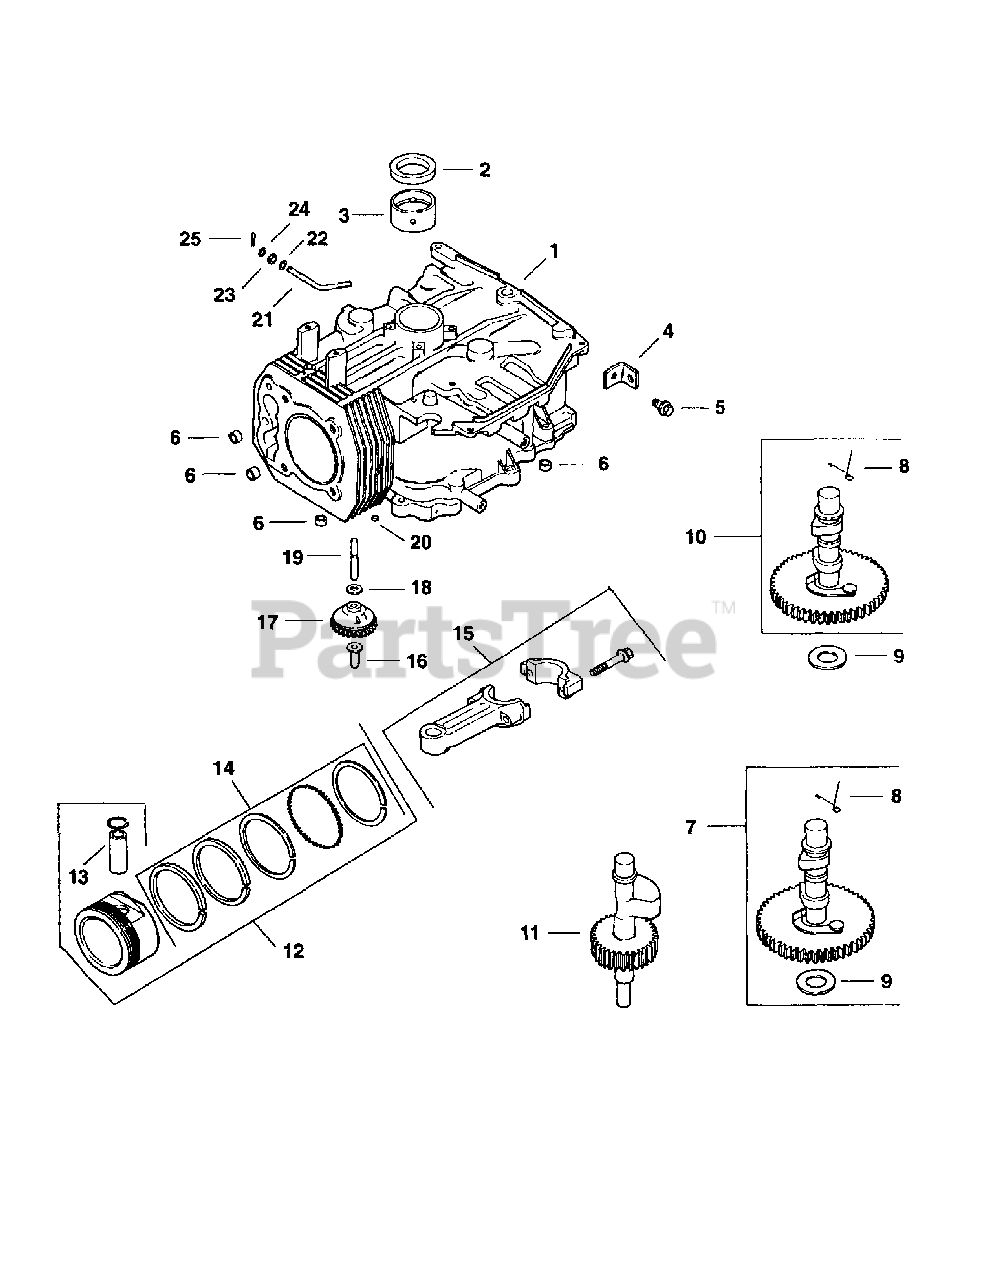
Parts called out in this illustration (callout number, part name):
1	Crankcase
2	Seal, Crankshaft
3	Bearing, Crankshaft (Std.)
3	Bearing, Crankshaft (.25)
3	Bearing, Crankshaft (.50)
4	Strap, Lifting
5	Screw, Lifting Strap M8 x 1.25 x 25
6	Dowel, Locating
7	Kit, Camshaft
8	Spring, Actuating (ACR)
9	Shim, Camshaft (A.R.) (White)
9	Shim, Camshaft (A.R.) (Blue)
9	Shim, Camshaft (A.R.) (Green)
9	Shim, Camshaft (A.R.) (Yellow)
9	Shim, Camshaft (A.R.) (Red)
9	Shim, Camshaft (A.R.) (Gray)
9	Shim, Camshaft (A.R.) (Black)
11	Shaft, Balance
12	Piston w/Ring Set (Std.)
12	Piston w/Ring Set (.25)
12	Piston w/Ring Set (.50)
13	Retainer, Piston Pin
14	Ring Set (Std.)
14	Ring Set (.25)
14	Ring Set (.50)
15	Connecting Rod (Std.)
15	Connecting Rod (.25)
16	Pin, Governor Regulating
17	Gear, Governor
18	Washer, Governor Gear Thrust
19	Shaft, Governor Gear
20	Plug, Cup
21	Governor Cross Shaft Kit
22	Washer, Plain 1/4"
23	Seal, Governor Cross Shaft
24	Washer, Governor Shaft
25	Pin, Governor Hitch
